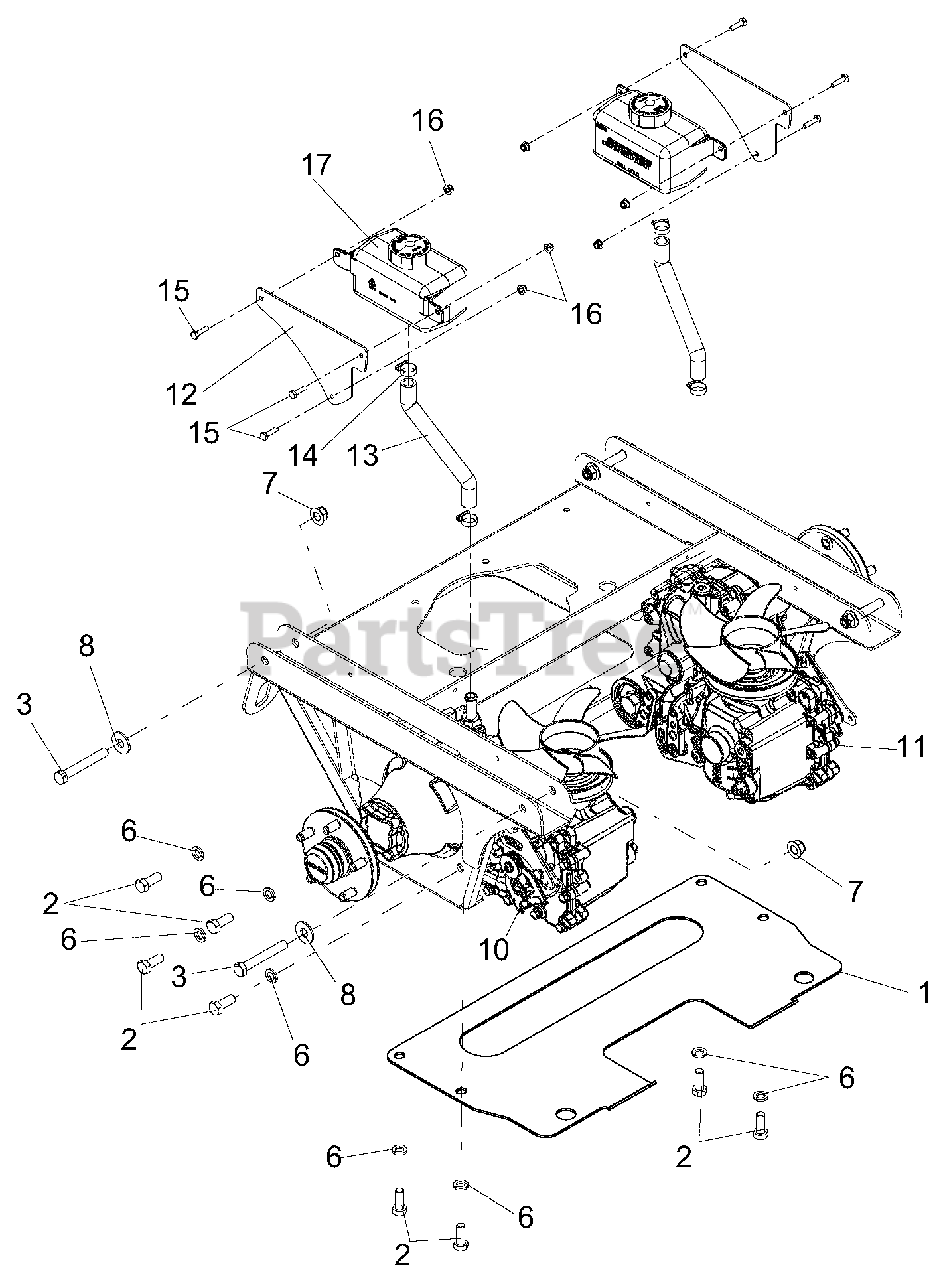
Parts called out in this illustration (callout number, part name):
1	PLATE, TRANSMISSION SKID
2	BLT-HEX .50-13X1.25 GR5 YWZC
3	BLT-HEX .50-13X3.50 GR5 YWZC
6	WSHR-LK .50X.125 REG YWZC
7	NUT-LK-NYL-FLG .50-13 YWZC
8	WSHR-FL-STL.563X1.38X.109YWZC
10	TRANS, R.H. HG ZT-5400
11	TRANS, LH HG ZT-5400
12	PLATE, HYDRO OVERFLOW TANK MTG
13	HOSE, HYDRO OVERFLOW
14	CLAMP, .88 DIA HOSE
15	BLT-HEX .25-20X1.00 GR5 YWZC
16	NUT-LK-NYL-FLG .25-20 YWZC
17	TANK, HYD 1000ML
